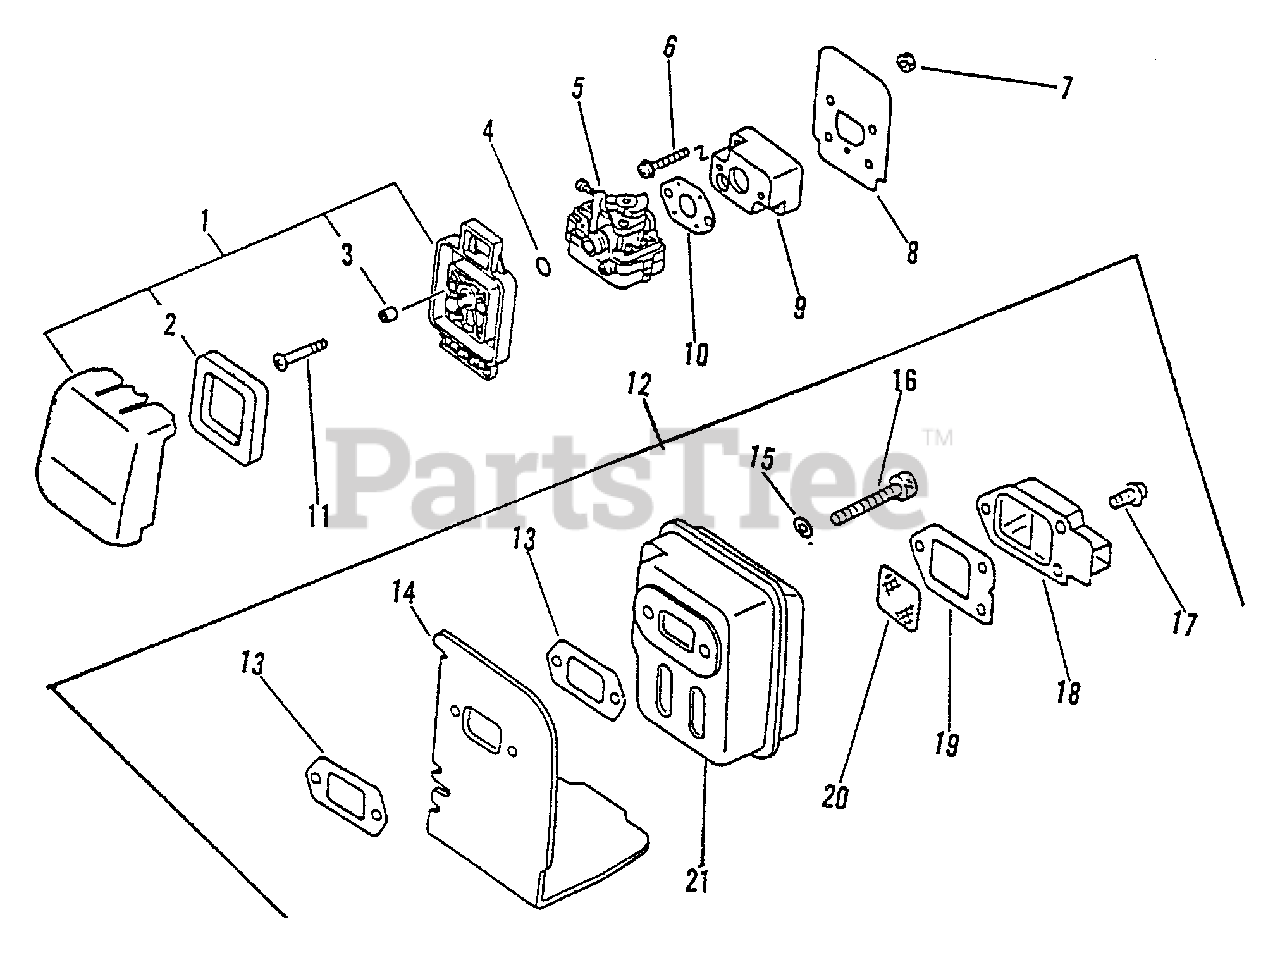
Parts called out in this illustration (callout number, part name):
1	AIR CLEANER ASSY
2	FILTER, AIR
3	SLEEVE
4	O-RING - 15
5	CARBURETOR WYL-6
6	SCREW - 5X22
8	SHIELD, INTAKE
9	INSULATOR, INTAKE
10	GASKET, INTAKE
11	SCREW - 5X64
12	MUFFLER ASSY
13	GASKET, EXHAUST
14	COVER, EXHAUST
15	WASHER - 5
16	SCREW - 5X55
17	SCREW - 4X10
18	GUIDE, EXHAUST - OUTER
19	GASKET, EXHAUST
20	SCREEN, SPARK ARRESTOR
